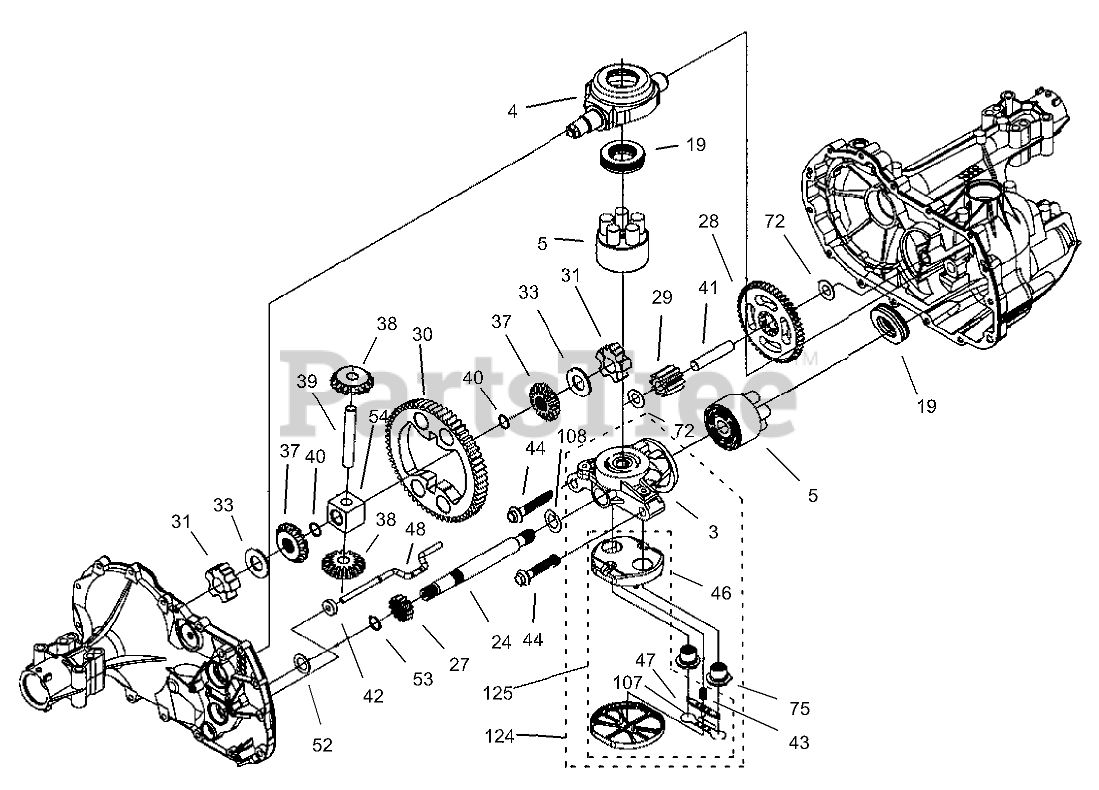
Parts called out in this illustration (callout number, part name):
3	CENTER SECTION ASM
4	SWASHPLATE-TRUNNION
5	CYLINDER BLOCK ASM
19	BEARING-THRUST
24	Shaft-Motor
27	GEAR-PINNION, 13T
28	GEAR-10T/48T
29	GEAR-JACKSHAFT, 10T
30	GEAR-BULL 60T
31	BEARING-SLEEVE
33	WASHER
37	GEAR-MITER
38	GEAR-MITER 15T
40	RING-RETAINING, SPIRAL
41	PIN-JACKSHAFT
42	MAGNET-RING
43	SPRING-BYPASS
46	BASE-FILTER
47	ACTUATOR-BYPASS
48	ROD-ACTUATOR, BYPASS
52	WASHER-FLAT
53	RING-RETAINING
54	BEARING-BLOCK, CENTER
72	WASHER
75	CHECK PLUG ASM
107	DEFLECTOR
108	WASHER
124	CENTER SECTION FILTER BYPASS ASM
125	FILTER ASM
